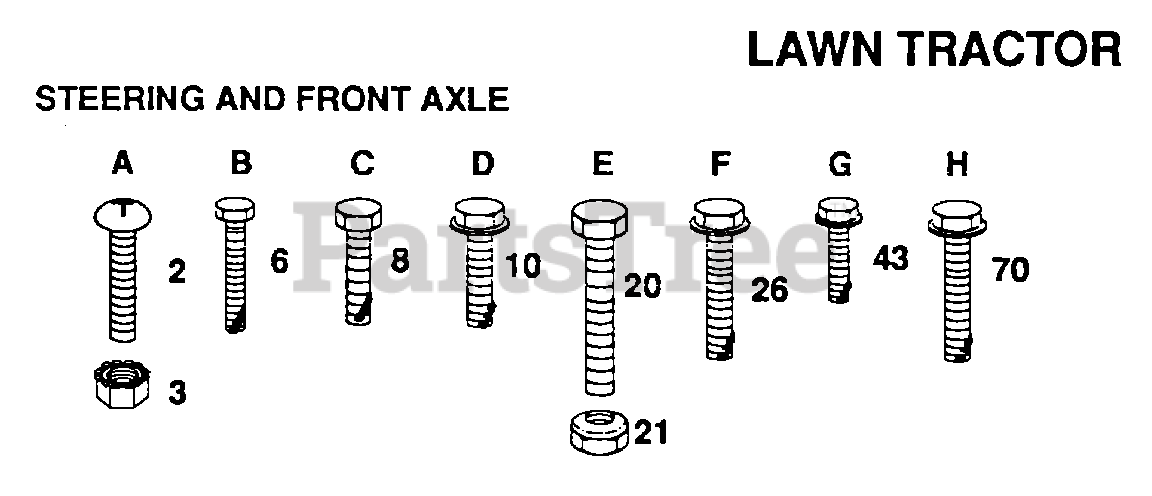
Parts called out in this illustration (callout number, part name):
2	SCREW
6	SCREW LT
10	SCREW LT
26	SCREW
43	SCREW LT
70	SCREW SPECIAL
